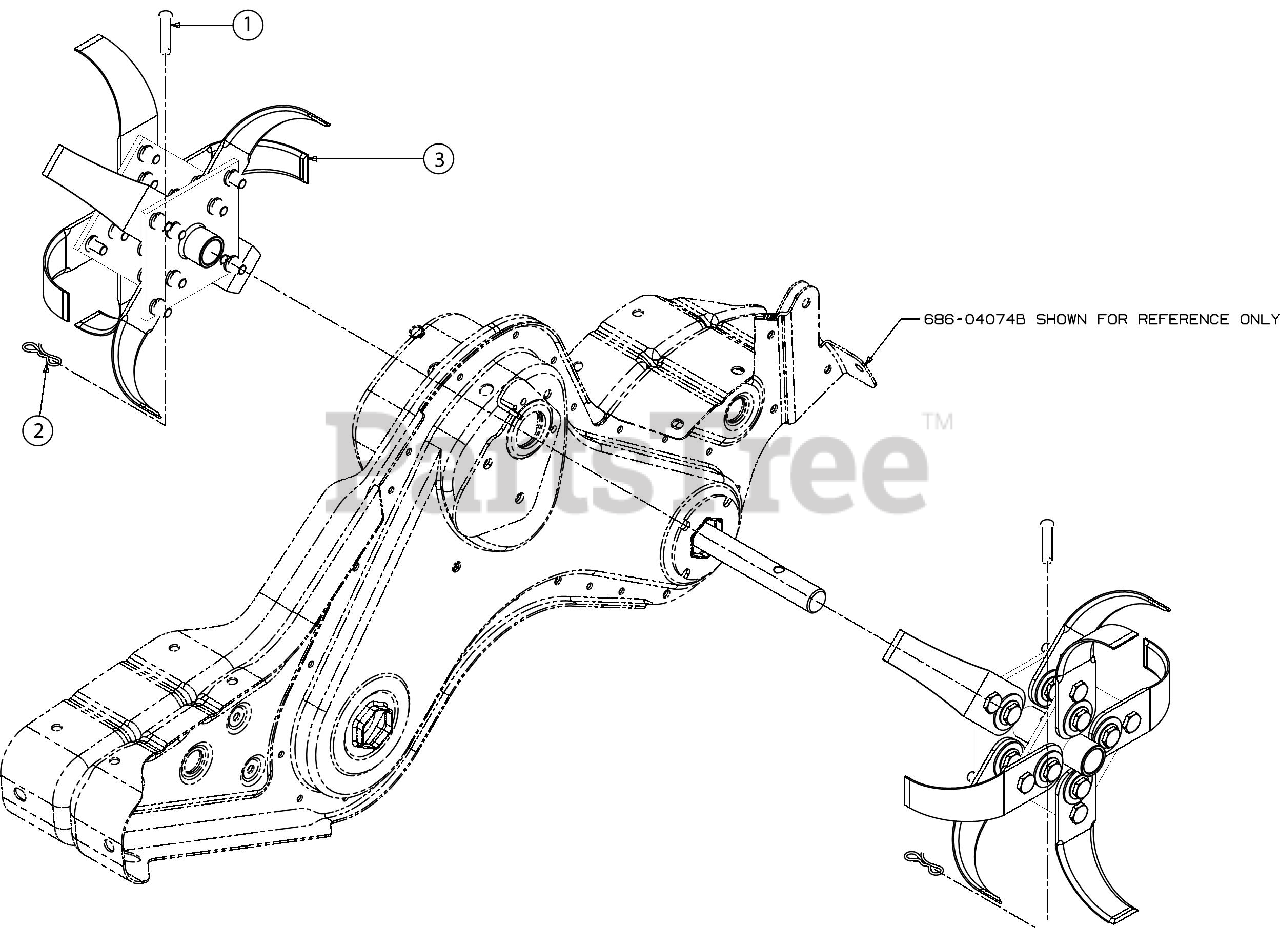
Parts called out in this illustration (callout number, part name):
1	CLEVIS PIN .375 X .1.75
2	PIN:COTTER
3	TINE ASSEMBLY
3	HEX LOCK NUT 3/8-2
3	LOCK WASHER 3/8
3	WASHER .51 X 1.5 X .07
3	BELL WASHER
3	SHOULDER SCREW
3	ARTICULATING TINE
3	TINE ADAPTER ASSEMBLY
3	TINE ADAPTER PLATE
